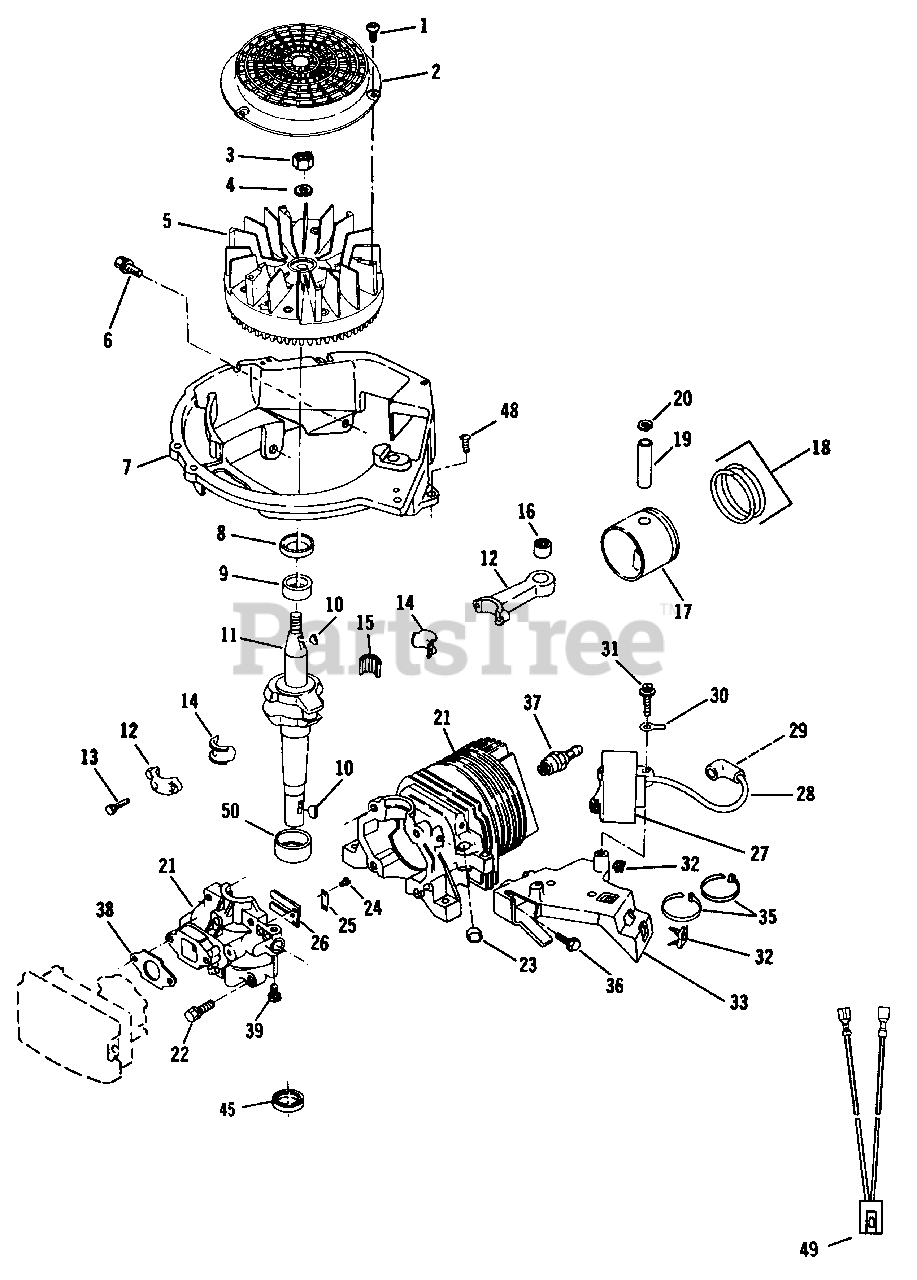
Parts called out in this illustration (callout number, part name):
1	Screw-Flywheel Screen
2	Screen-Flywheel
3	Nut-Flywheel
4	Lockwasher
5	Flywheel Assembly
6	Screw
7	Base-Shroud
8	Oil Seal-Upper
9	Bearing-Upper
10	Key-Flywheel
11	Crankshaft
12	Connecting Rod Assembly
13	Screw Lever
14	Liner-Split
15	Needle Bearing Set
16	Bearing Assembly
17	Piston and Ring Set
18	Ring Set
19	Wrist Pin
20	Retaining Ring
21	Cylinder and Crankcase Cover Assembly
22	Screw-Cover to Crankcase
23	Plug
24	Screw-Reed to C'case Cover
25	Plate-Reed Hold Down
26	Reed
27	C.D. Ignition Module and Lead Assembly
28	High Tension Lead and Cover Assembly
29	Spring Terminal
30	Terminal-Ground Lead
31	Screw-C.D. Mounting
32	Grommet-C.D. Bracket
33	Bracket-Ignition Mtg.
35	Tie Strap
36	Screw
37	Spark Plug
38	Gasket-Carb. to Crankcase Cover
39	Set Screw-Starter Assembly
45	Oil Seal-Crankshaft
48	Screw-Shd. Base to C.D. Brk't.
49	Wire Harness-Engine
50	Bearing-Lower
